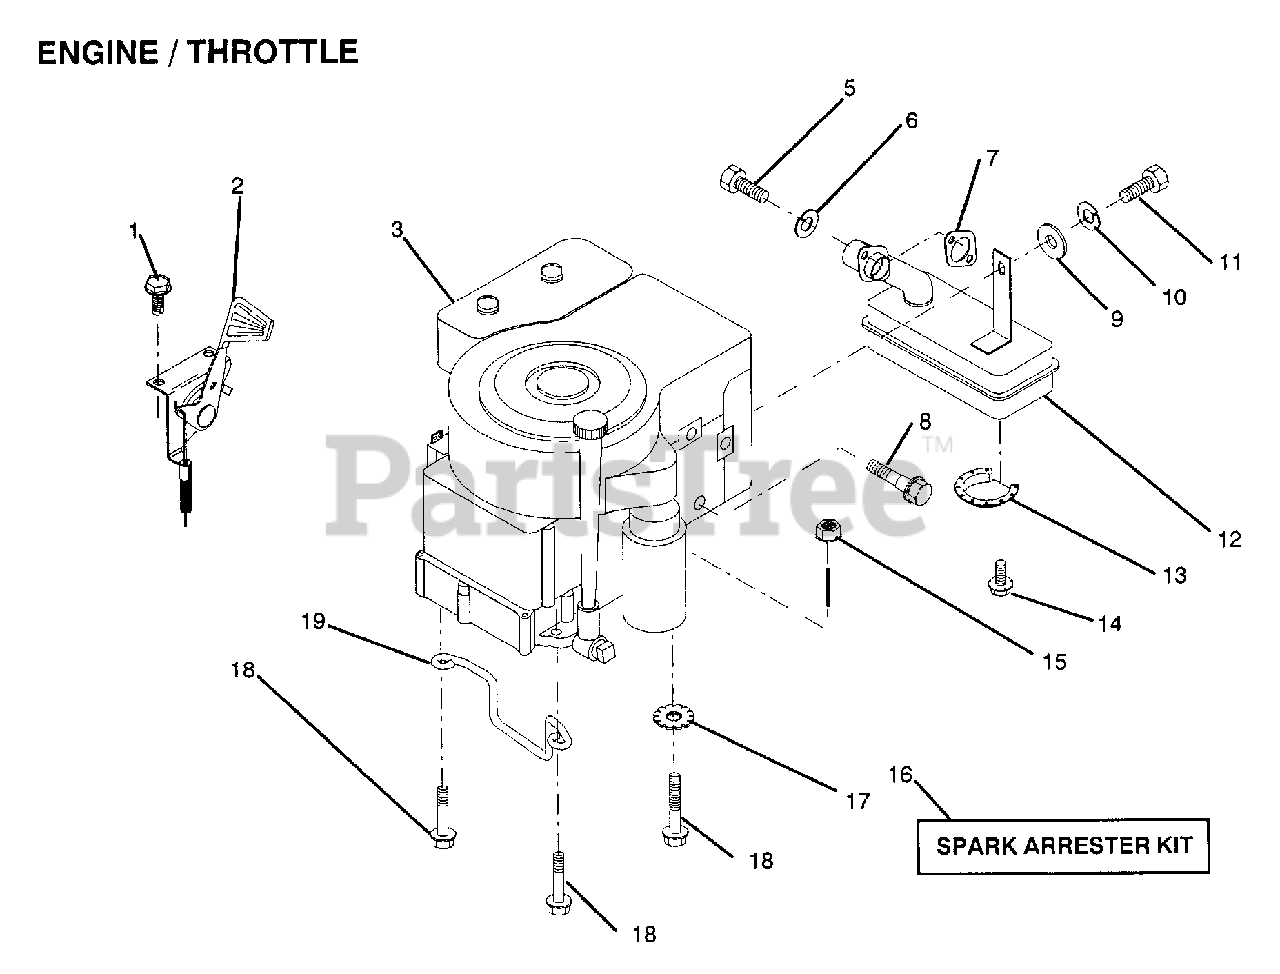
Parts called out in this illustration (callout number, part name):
1	SCREW
3	ENGINE, BRIGGS AND STRATON
5	SCREW
6	LOCKWASHER
8	BOLT T
10	LOCKWASHER
12	MUFFLER
13	DEFLECTOR.222573
15	NUT
17	LOCKWASHER
18	SCREW LT
19	"KEEPER,DR BELT GR"
